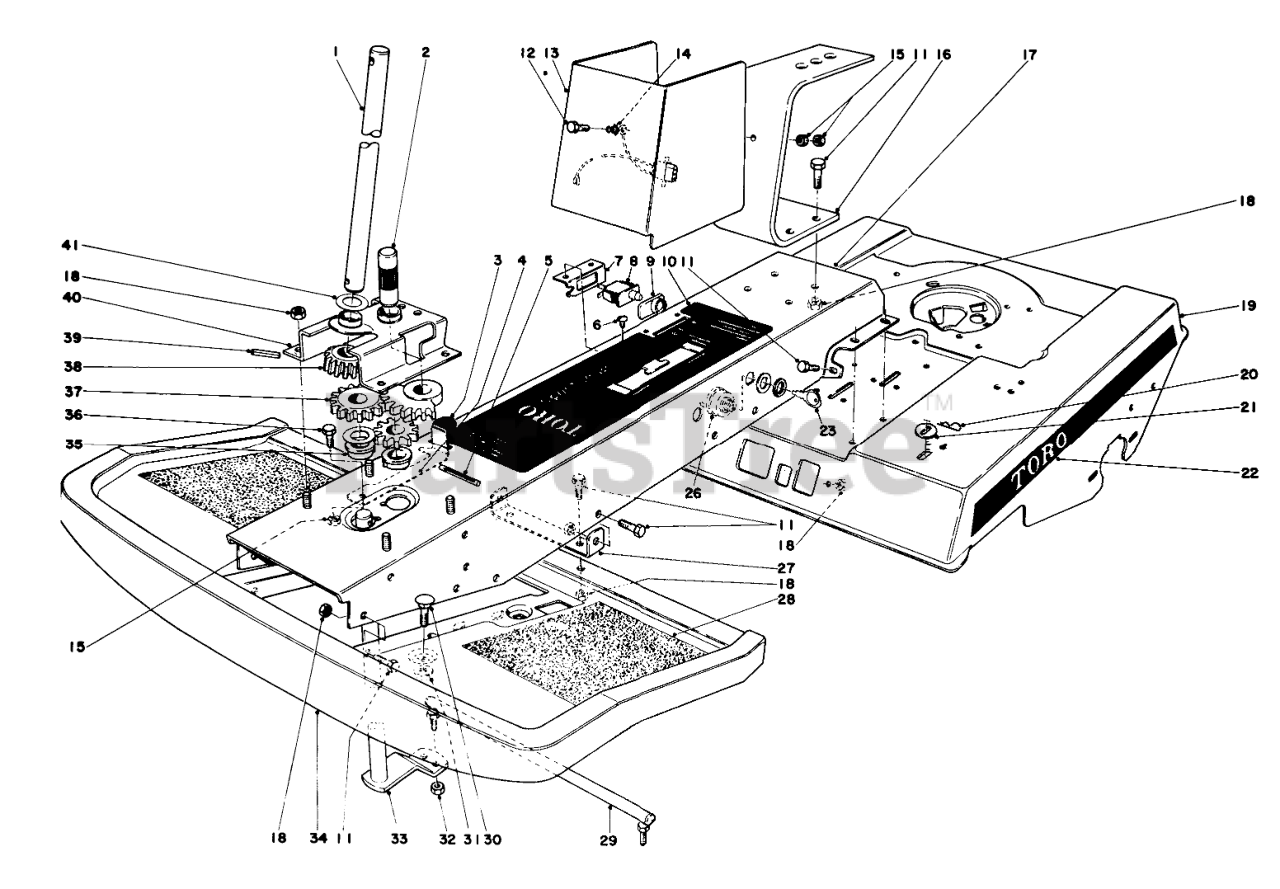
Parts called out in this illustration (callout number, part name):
1	Shaft Upper
2	Steering Idler Ass-y.
3	Parking Brake Tip
4	Parking Brake Spring
5	3/16 X 1-1/2 GRVE PIN
6	SCREW-HWHTF
7	Switch Bracket
8	Switch
9	Boot Switch
10	Decal Throttle Control (Model 56005)
11	SCREW-HH
12	SCREW-HH
13	Cover Seat
14	WASHER-LOCK/EXT
15	NUT-LOCK, CONE
16	Seat Spring
17	Frame Center Member
18	NUT-LOCK, CONE
19	Engine Mounting Frame
20	PIN-COTTER
21	Washer
22	Decal L.H.
23	Key
26	Switch
27	Support
28	Foot Tread
29	Ball Joint
30	SCREW-CARR
31	NUT-HF
32	NUT-LOCK, NI
33	Shaft
34	Foot Rest
35	Bushing
36	SCREW-HH
38	STEERING PINION
39	PIN-ROLL, SLOTTED
40	Bracket Steering Support
41	Washer
